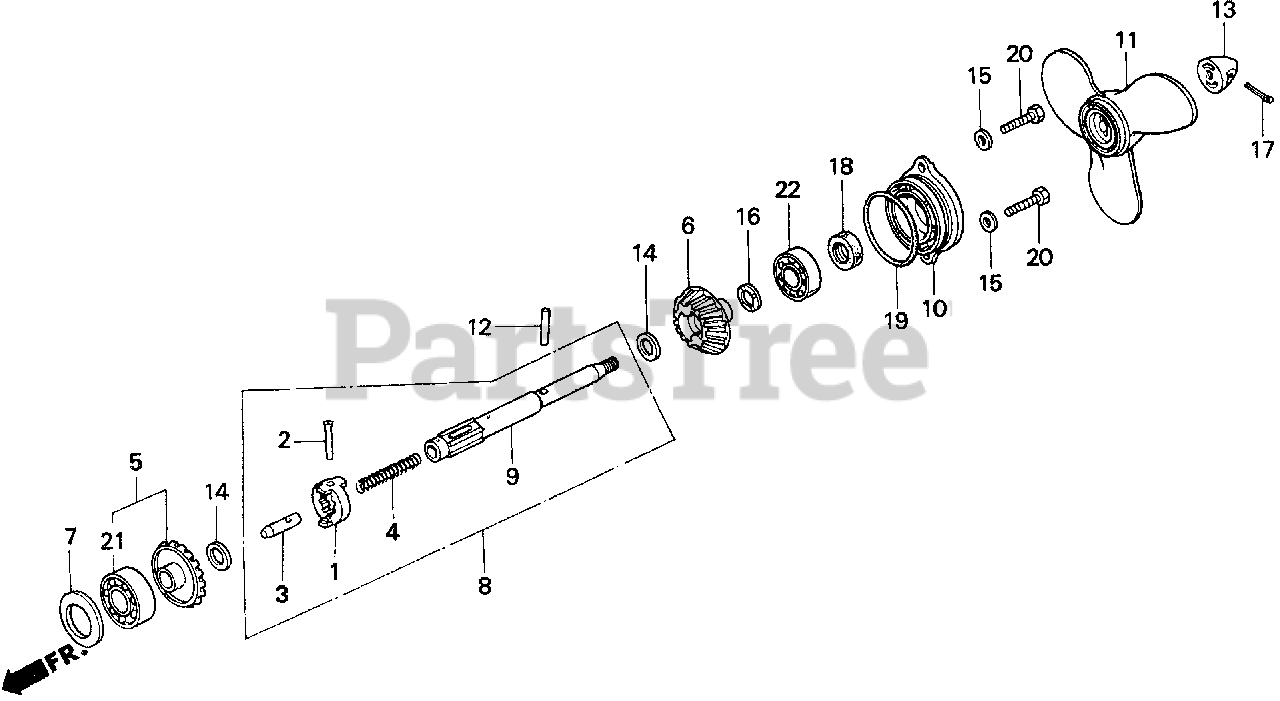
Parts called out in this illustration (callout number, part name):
1	SHIFTER, CLUTCH
2	PIN, SHIFTER (4X35)
3	SLIDER, SHIFT
4	SPRING, SHIFT
5	GEAR, FR. BEVEL
6	GEAR, RR. BEVEL
7	SHIM A, GEAR (0.10MM)
7	SHIM B, GEAR (0.15MM)
8	SHAFT, PROPELLER
9	SHAFT, PROPELLER
10	HOLDER, PROPELLER SHAFT *B107* (SENIOR BLUE) (NOT AVAILABLE)
11	PROPELLER, THREE-BLADE *Y35* (CALYPSO YELLOW)
11	PROPELLER, THREE-BLADE *NH283* (STIN GRAY)
12	PIN, SHEAR
13	CAP, PROPELLER
14	WASHER (17MM)
15	WASHER, PLAIN (6MM)
16	WASHER C, GEAR (2.10MM)
16	WASHER D, GEAR (2.15MM)
17	PIN, COTTER (3MM)
18	SEAL, WATER (17MM)
19	O-RING (66X2.5)
20	BOLT, HEX. (6X20)
21	BEARING, RADIAL BALL (6005)
22	BEARING, RADIAL BALL (6203)
